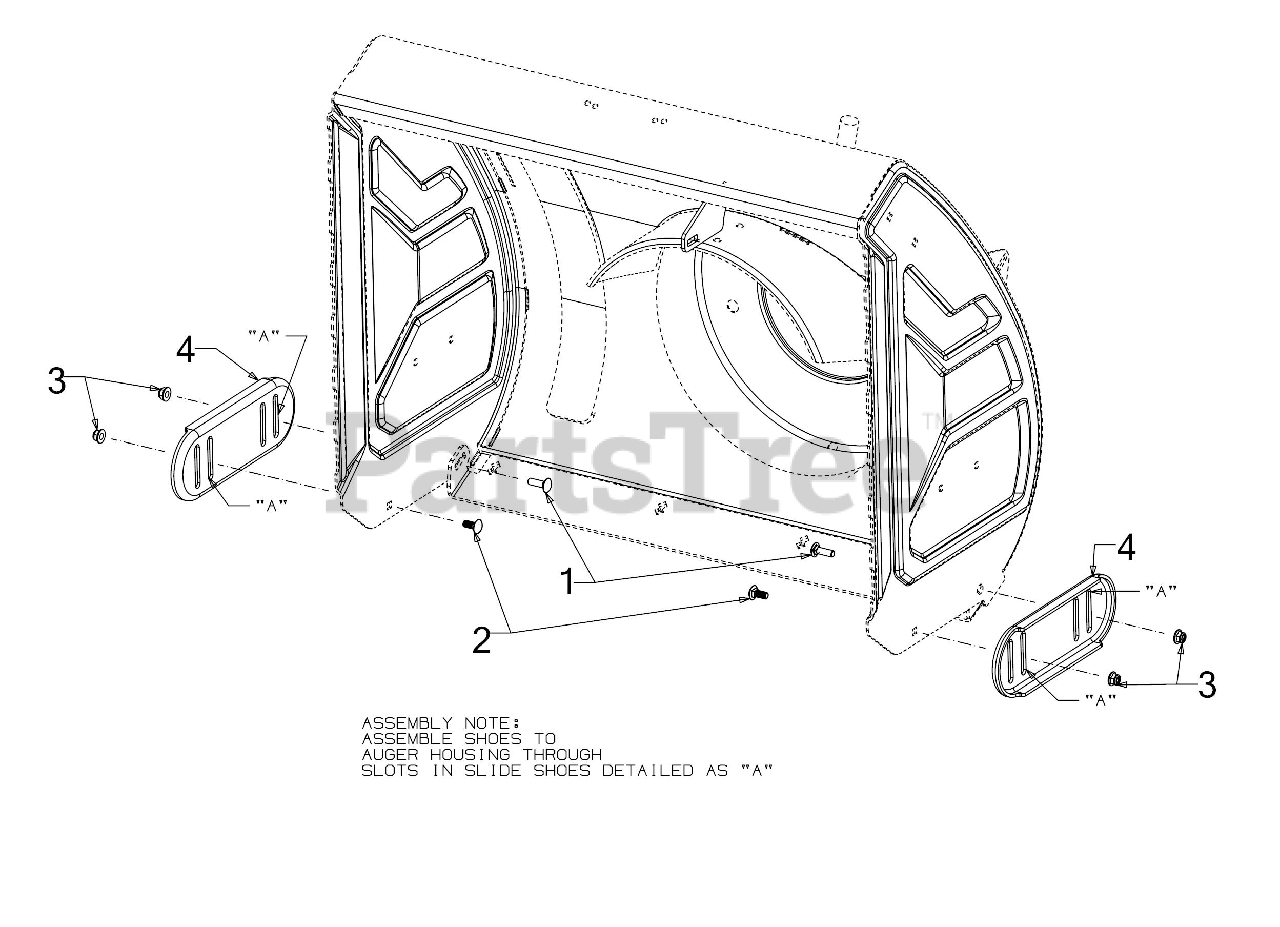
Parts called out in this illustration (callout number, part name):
1	CARRIAGE BOLT 5/16-18 x 1.00
2	CARRIAGE BOLT 5/16-18 x .75
3	FLANGE LOCK NUT 5/16-18
4	SLIDE SHOE
